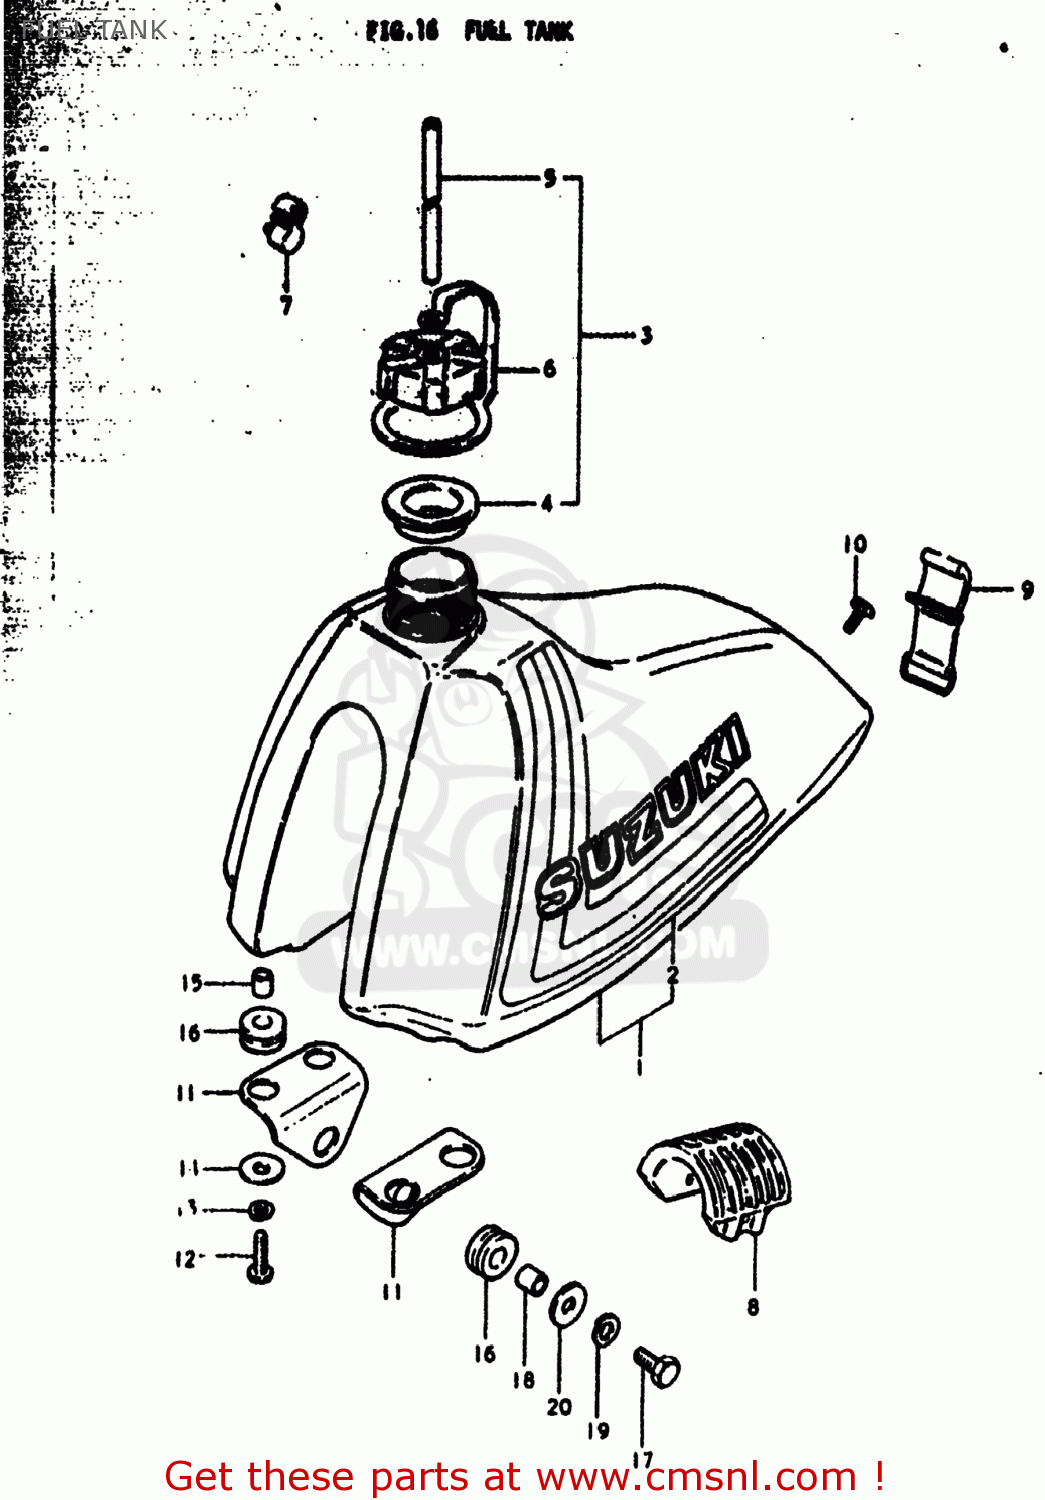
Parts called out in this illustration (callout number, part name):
1	TANK ASSEMBLY,FUEL
3	CAP SET,FUEL TANK
4	GASKET,FUEL TANK CAP (NAS)
5	HOSE
6	BAND,FUEL TANK CAP
7	CLAMP,FUEL TANK BREATHER HOSE
8	CUSHION,FUEL TANK
9	BAND
10	SCREW(6X18)
11	BRACKET,FUEL TANK
12	SCREW
13	LOCK WASHER
14	WASHER (6.5X24X1.6)
15	SPACER(6.8X12X11)
16	CUSHION
17	BOLT
18	SPACER (8.8X12X11)
19	LOCK WASHER
20	WASHER (8.2X24X1.6)
